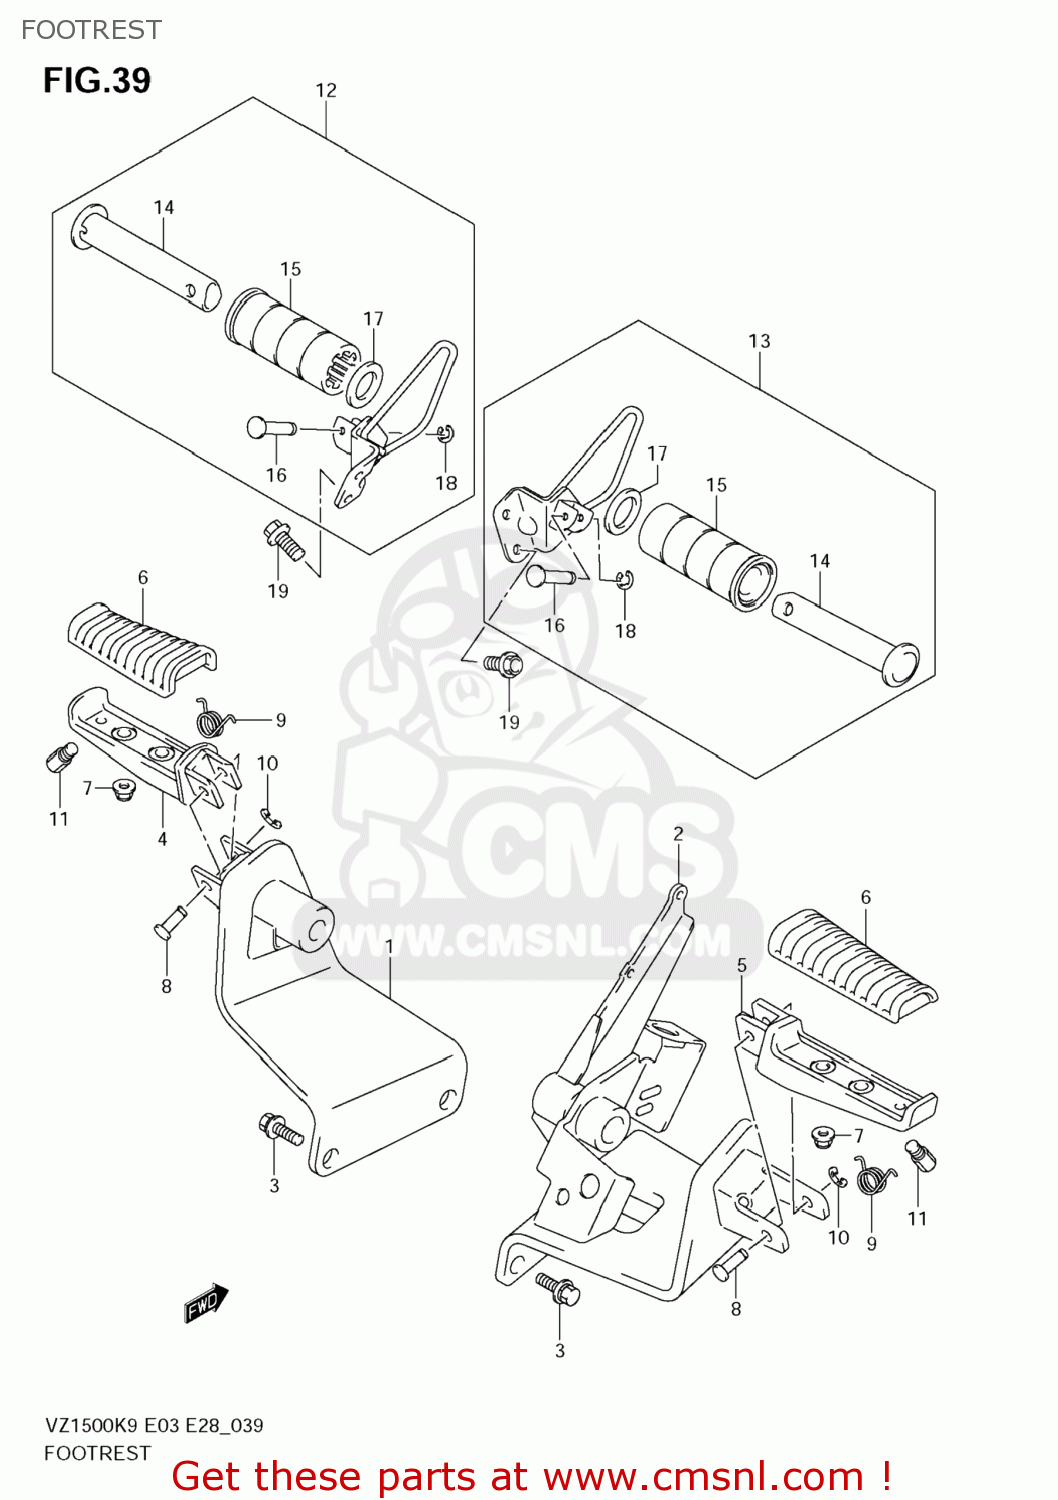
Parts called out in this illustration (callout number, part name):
1	BRACKET,FR FOOTREST,R
2	BRACKET,FR FOOTREST,L
3	BOLT(10X25)
4	BAR,FR FOOTREST,R
5	BAR,FR FOOTREST,L
6	RUBBER,FR FOOTREST
7	NUT
8	PIN(8X33.2)
9	SPRING
10	E RING
11	BOLT,BANK SENSOR
12	FOOTREST ASSY,PILLION,R
13	FOOTREST ASSY,PILLION,L
14	BAR,PILLION FOOTREST
15	RUBBER,PILLION FOOTREST
16	PIN
17	WASHER(19.5X32X2)
18	E RING
19	BOLT(8X16)
